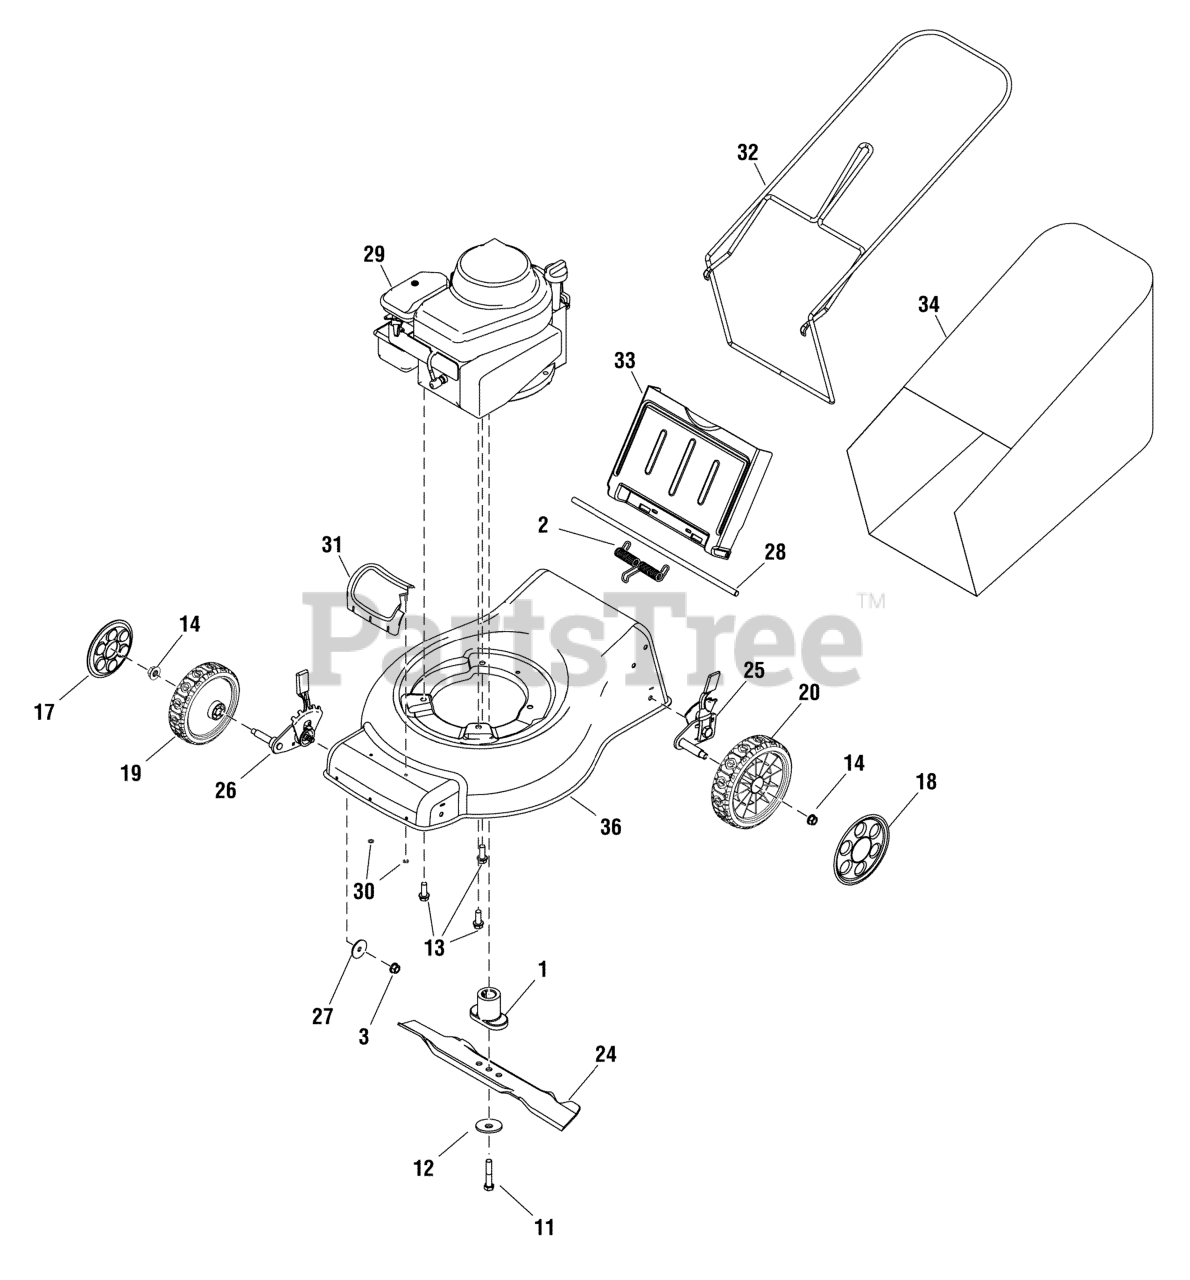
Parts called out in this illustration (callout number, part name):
1	BLADE, Adapter
2	SPRING, Torsion
3	NUT, Lock, Nylon, M8 - 1.25
11	BOLT, 3/8-24, G8
12	WASHER, Belleville
13	SCREW, Self Tap, 3/8-16
14	NUT, Flange, 3/8-16
17	HUBCAP, 150mm
18	HUBCAP, 175mm
19	WHEEL ASSEMBLY, No Bearing, 150mm
20	WHEEL ASSEMBLY, No Bearing, 175mm
24	BAR BLADE, 16"
25	HEIGHT ADJUST ASSEMBLY, LH
26	HEIGHT ADJUST ASSEMBLY, RH
27	WASHER, Flat
28	ROD, Rear Door
29	* ENGINE, Briggs & Stratton
30	NUT, Retainer, M4
31	COVER, Front
32	FRAME, Bag
33	DOOR, Rear
34	BAG
36	HOUSING ASSEMBLY, 16"
